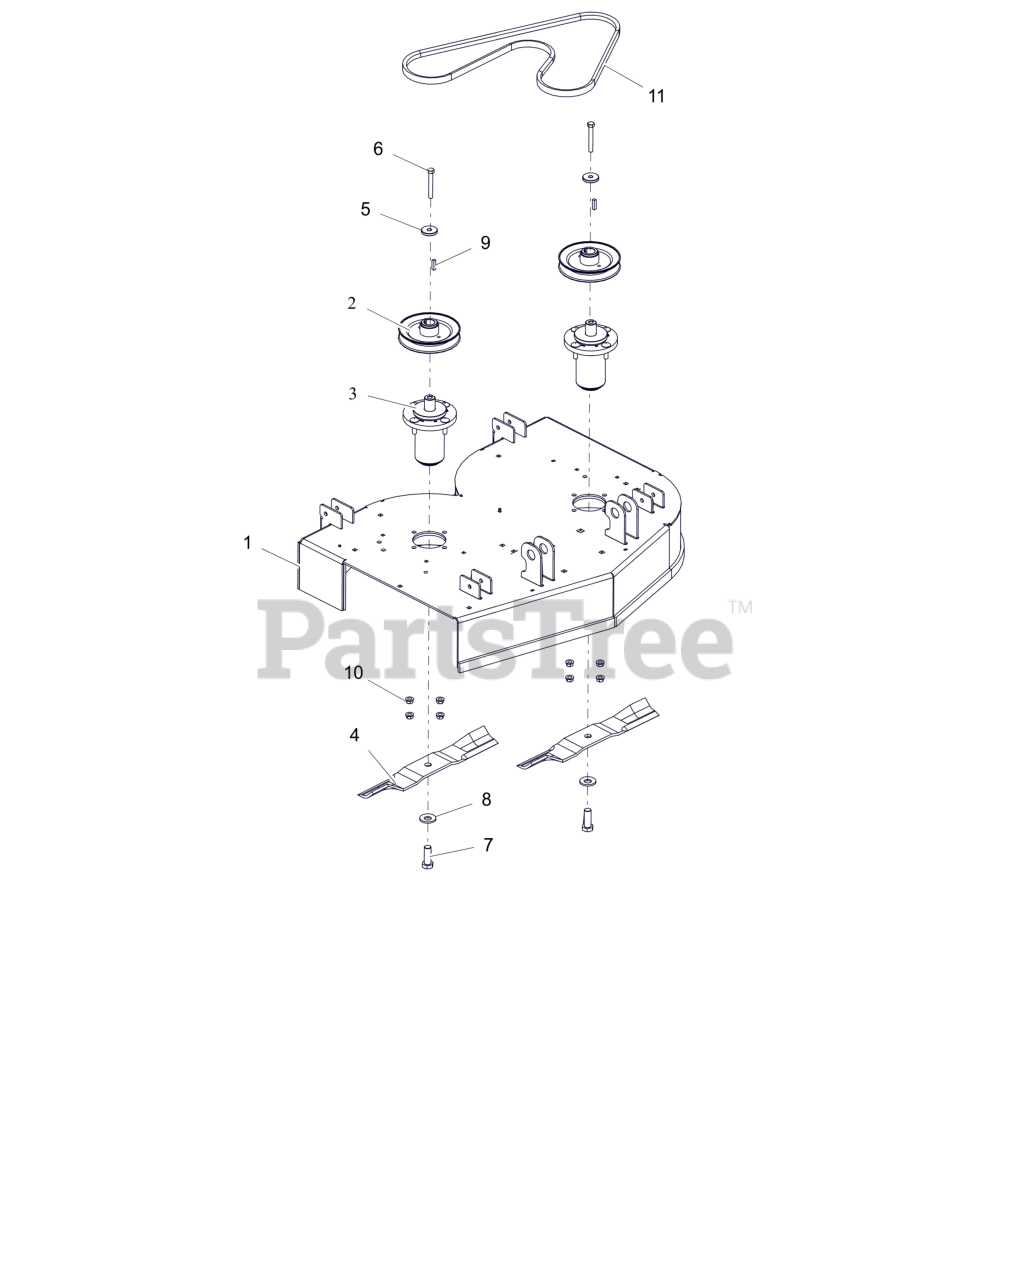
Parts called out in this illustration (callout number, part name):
1	WLDMT, 32" PRO STANCE DECK (RED)
2	PULLEY, V - 1.000 ID X 5.750 OD
3	ASM, MAINT FREE ALUM SPINDLE
4	BLADE, 16.19" MOWER (HI-LIFT)
5	RETAINER, SHEAVE
6	BLT, HEX .38-16X2.75 G8 ZCC
7	BLT, HEX .62-18X1.75 G8 ZCC
8	WSHR-BLVL .669X1.535X.138
9	KEY, SQ .25X.25X1.00 RC 40-50
10	NUT-LK-CTR-FLG .375-16 GF ZCC
11	V-BELT, 5L RAW EDGE EPDM
